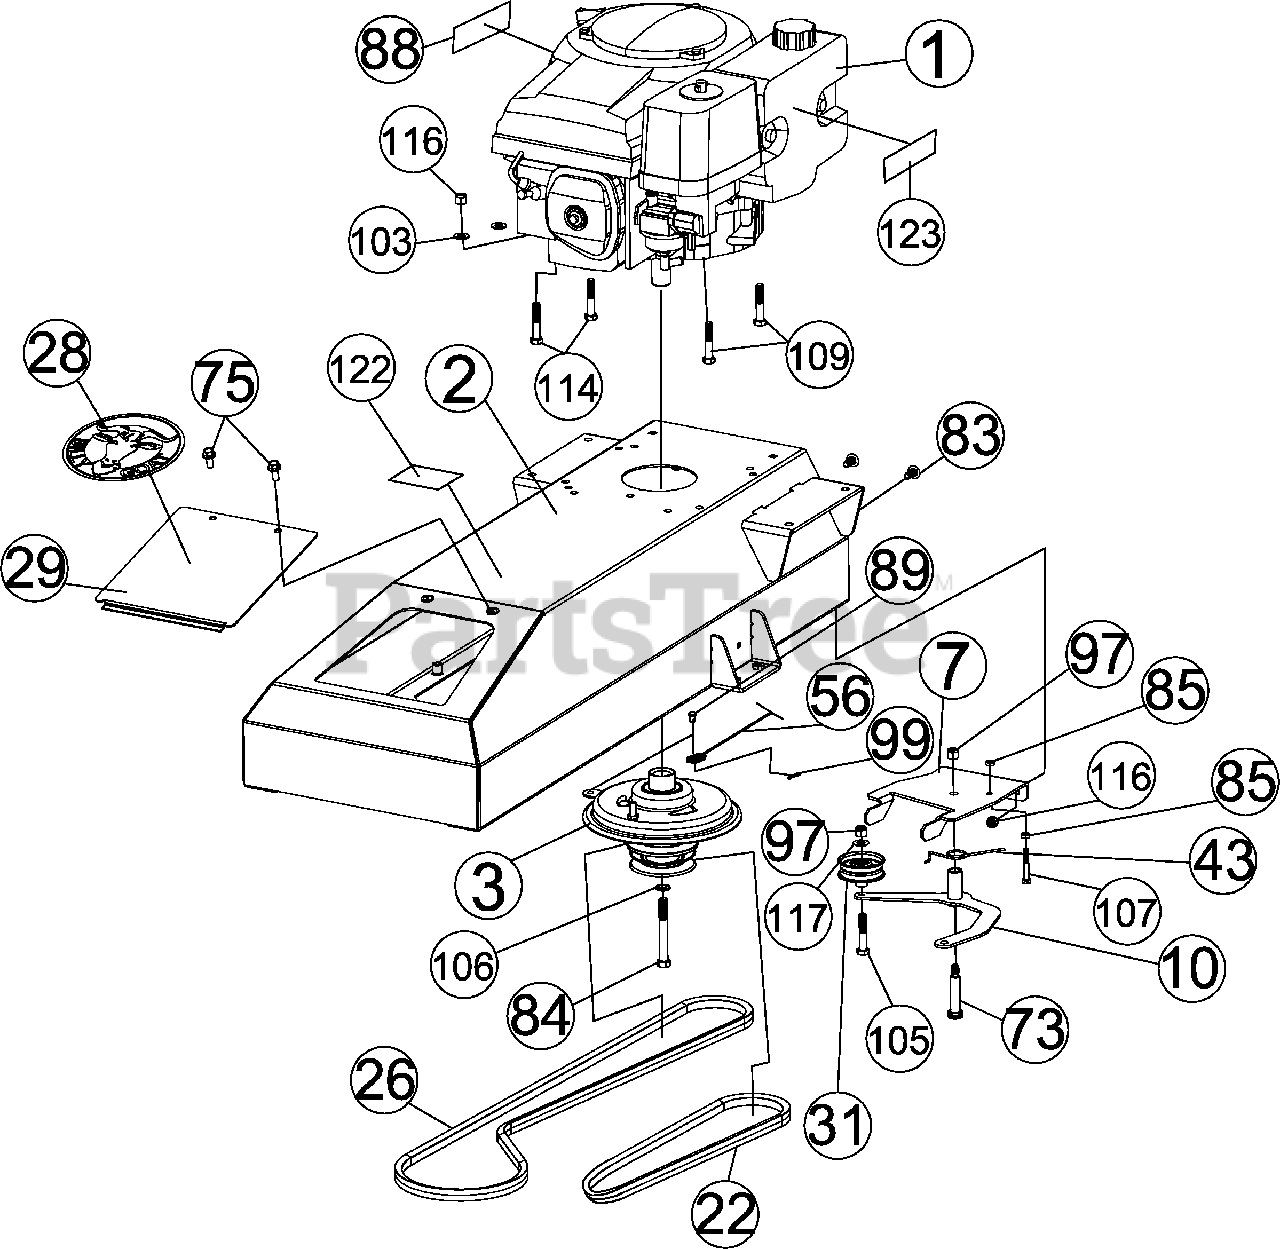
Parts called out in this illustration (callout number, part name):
1	ENGINE 13HP HONDA GX390UTQA2
2	BASE ENGINE BC26 FIXED WA W/LABELS
3	CLUTCH
7	BRACKET BELT TIGHTEN BC26
10	ARM IDLER DRIVE MECH WA
22	BELT 6830 POWERATED
26	BELT 6972 POWERATED
28	LABEL PRODUCT DECAL LG CIRCLE
29	DOOR BASE ENGINE BC
31	PULLEY IDLER ARM HP
43	SPRING TRANS IDLER
56	CABLE CLUTCH BC26
73	BOLT SHOULDER 1/2" X 2"
75	SER HEX WSHR FLNG SCR 5/16"-18 X 3/4"
83	BOLT CARRIAGE 5/16"-18 X 3/4" ZP
84	SCREWCAP 7/16" -20 X 3 1/2" GR. 8 W/PATCH
85	NUT JAM 1/4" NC HEX
88	LABEL WARNING FUEL EN/SP
89	PIN CLEVIS .25 X .050
97	NUT LOCK 3/8"-16 HEX
99	PIN HITCH CLIP .051 X 3/4"
103	WASHER 5/16" FLAT ZP
105	SCREWCAP 3/8"-16 X 2" HCS ZP
106	WASHER LOCK 7/16" S/T MED
107	SCREWCAP 1/4"-20 X 1 3/4" HCS ZP
114	SCREWCAP 5/16"- 18 X 1 3/4" GR. 5 HCS ZP
116	NUT LOCK 5/16"-18 HEX ZP
117	WASHER 3/8" SAE
122	LABEL GUARDS
123	LABEL SPARK ARRESTOR
